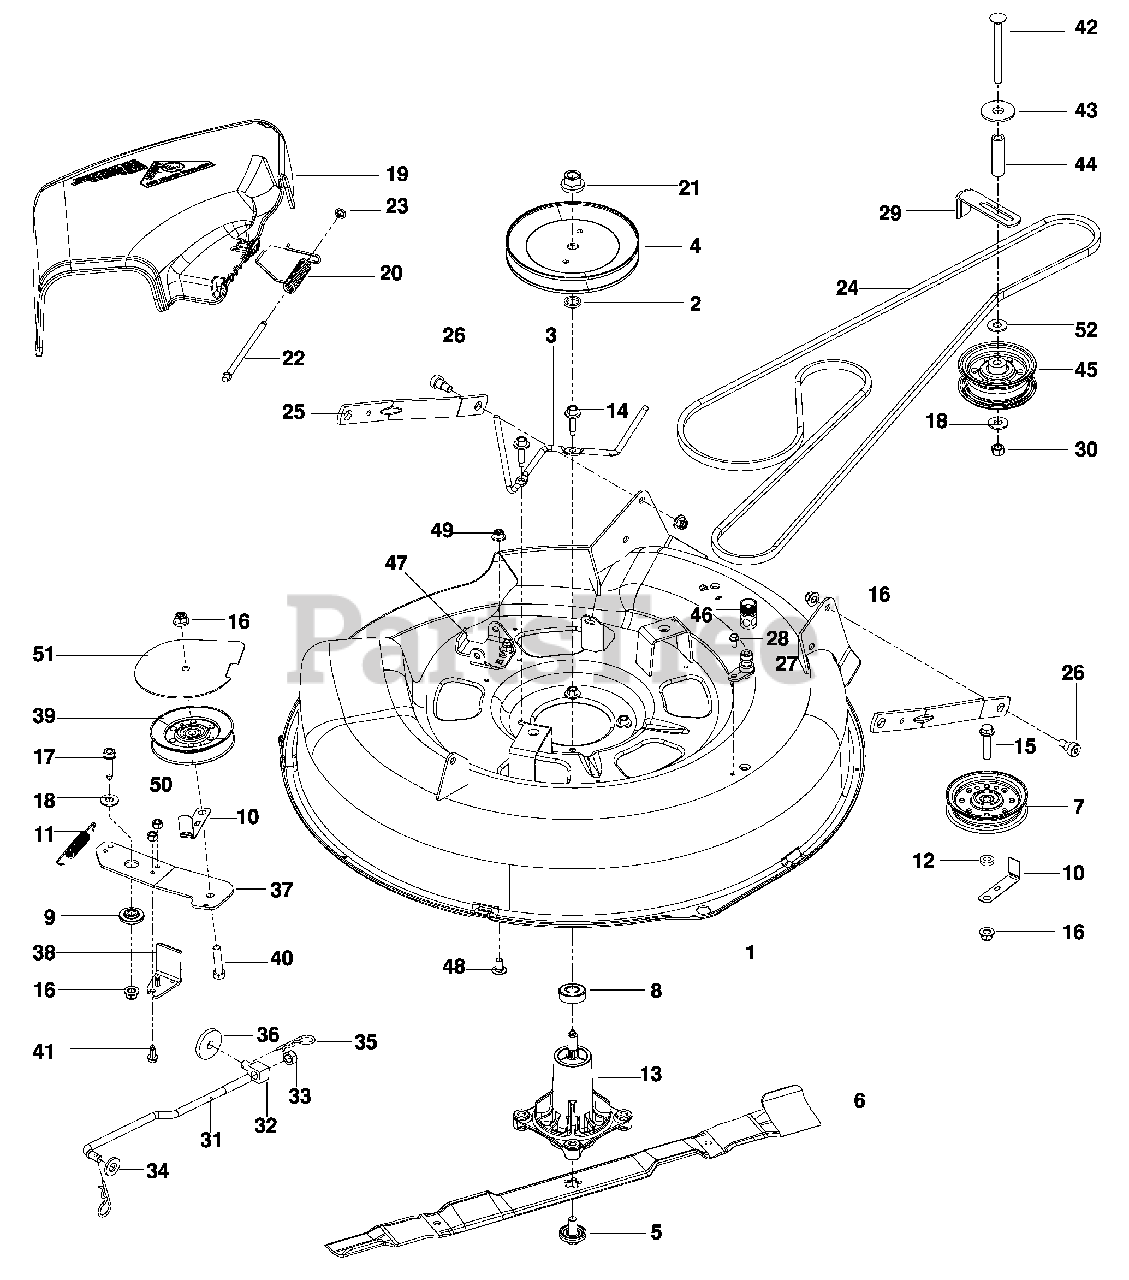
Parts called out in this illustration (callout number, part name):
1	DECK w/ DECALS
2	WASHER/SPACER
3	KEEPER, BELT
4	PULLEY, MANDREL
5	BOLT/WASHER ASSY
6	BLADE, MOWER/MULCH
7	PULLEY, IDLER
8	BEARING, BALL
9	SPACER RETAINER
10	KEEPER, BELT
11	SPRING RETURN
12	WASHER 3/8 x ¾
13	MANDREL ASSY
14	SCREW 5/16-18 WASHER HD
15	BOLT 3/8-16 x 1 ¾ WHIZLK
16	NUT 3/8-16 FLANGE NYLOC
17	BOLT 3/8-16 x 1½ THD FRM
18	WASHER 3/8 FLAT STD
19	CHUTE, DISCHARGE
20	SPRING, TORSION
21	NUT 9/16 TOP CENTER LOCK
22	ROD, HINGE
23	NUT 5/16 PUSH
24	BELT, DECK
25	ARM, DECK SUSPENSION
26	BOLT 3/8-16 x 3/8 SKT HD
27	WASHOUT PORT
28	BOLT ¼-20 x ½ HWST
29	GUIDE, BELT
30	NUT 3/8-16 HEX NYLOC
31	LINK, SUSPENSION
33	NUT 7/16-20 HEX NYLOC
34	WASHER ½ SAE
36	WASHER 1¾ x ¼ HEAVY
37	ARM, IDLER
38	ARM, LH BRAKE
39	IDLER V-GROOVE
40	BOLT, HEX HD 3/8-16 x 1½
41	SCREW ¼-20 x 5/8 THDROLL
42	BOLT, RD HD 3/8-16 x 4
43	WASHER 7/16 FLAT
44	SPACER .390 ID x 2¼
45	PULLEY, DECK IDLER
46	COUPLING, QUICK DISC
47	BRACKET, DEFLECTOR
48	BOLT, RD HD 5/16-18 x 5/8
49	NUT 5/16-18 FLANGE NYLOC
50	NUT ¼-20 HEX NYLOC
51	COVER, PULLEY
52	WASHER 3/8
